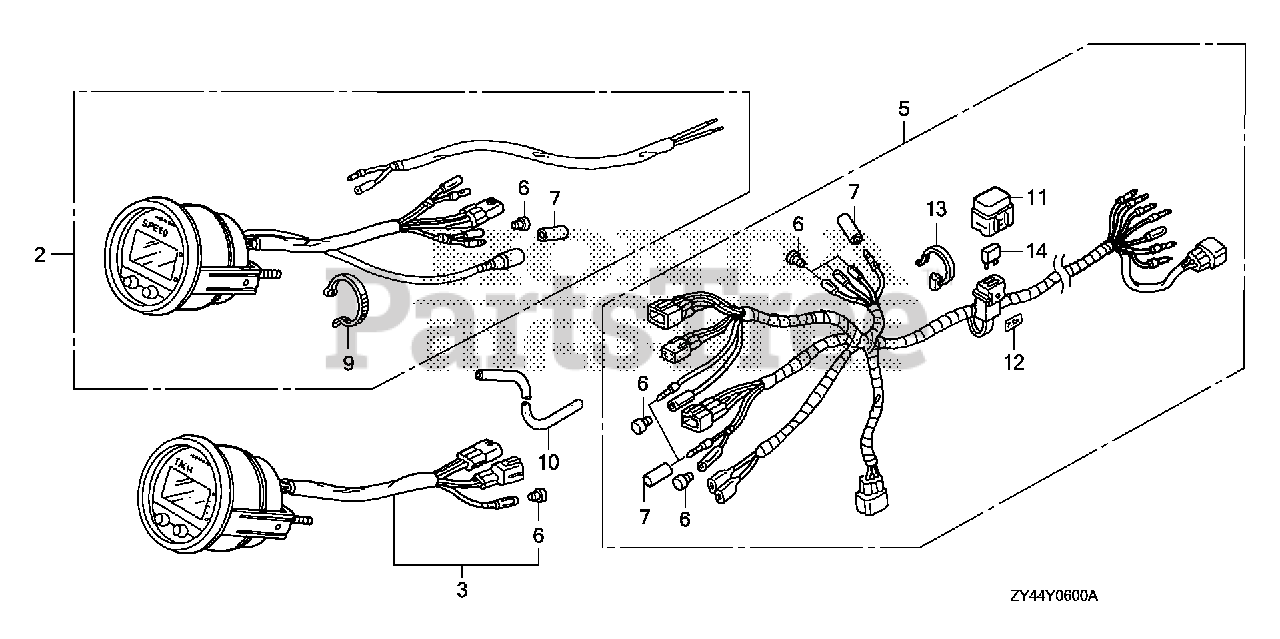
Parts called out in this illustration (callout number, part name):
1	HARNESS KIT, METER (DIGITAL) (INCLUDE 32540-ZY3-802)
2	SPEEDOMETER KIT (DIGITAL)(USA) (NOT AVAILABLE)
3	METER KIT, TACHO (DIGITAL)(USA) (NOT AVAILABLE)
3	METER KIT, TACHO (DIGITAL) (USE FOR 32540-ZY3-800/801)
4	WIRE ASSY., INDICATOR (DIGITAL)
5	HARNESS ASSY., METER (A)(DIGITAL)
6	PLUG, CONNECTOR (INNER)
7	PLUG, CONNECTOR (OUTER)
8	TIE, CABLE (2.4X92) (NATURAL)
9	BAND (BLACK 3.5X140)
10	TUBE, SPEED METER (4X7X8000)
11	COVER ASSY., FUSE (7.5A)
12	MARK, FUSE (7.5A)
13	TIE, CABLE
14	FUSE, BLADE (7.5A)
